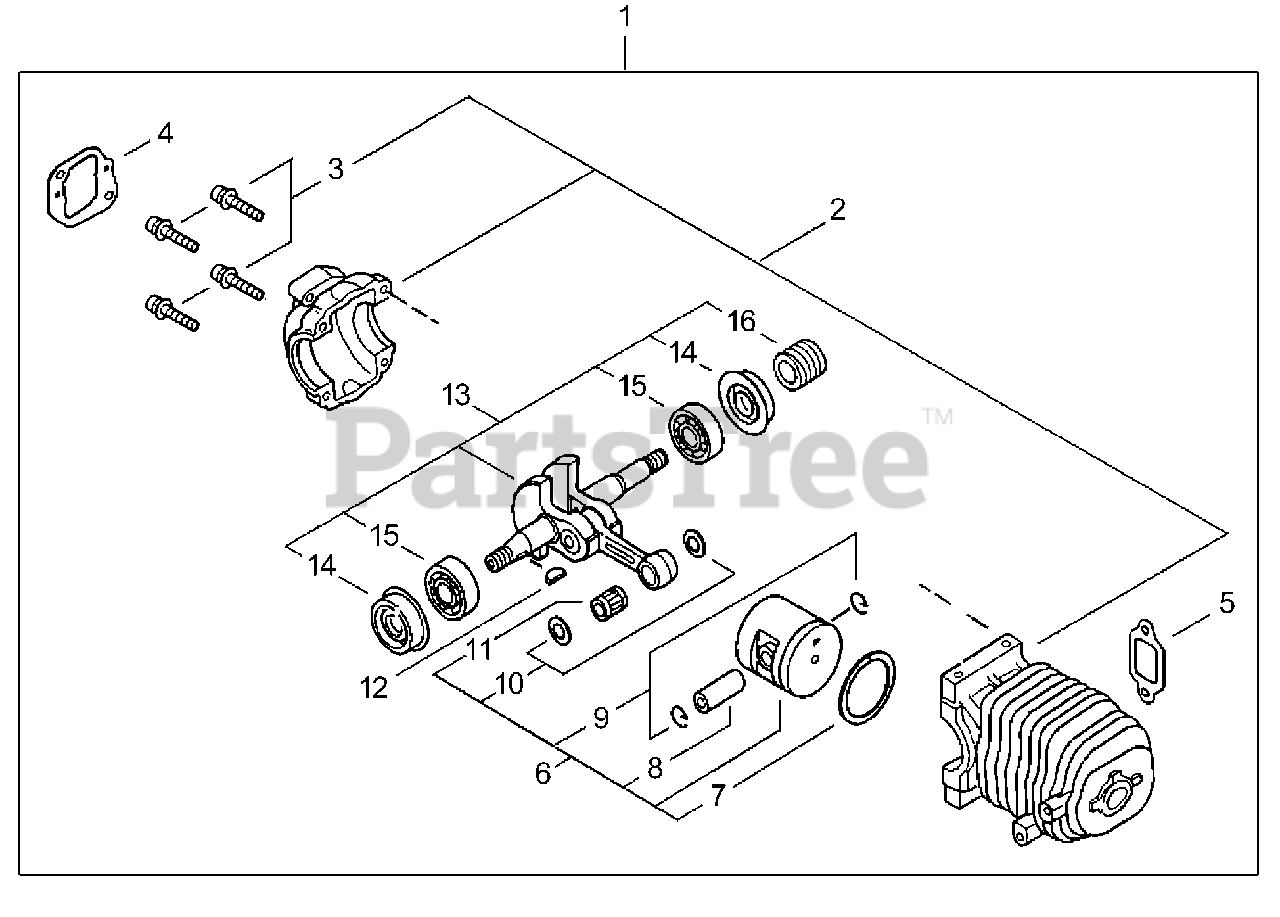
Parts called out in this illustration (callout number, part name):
1	SHORT BLOCK CS-3000
2	CYLINDER & CRANKCASE ASSY
3	SCREW 5×25
4	GASKET, INTAKE
5	GASKET, MUFFLER
6	PISTON KIT
7	RING, PISTON
8	PIN, PISTON
9	RING, SNAP
10	WASHER, THRUST
11	BEARING, NEEDLE 8
12	KEY, WOODRUFF
13	CRANKSHAFT ASSY
14	SEAL, OIL 12
15	BEARING, BALL - 6201 C3
16	GEAR, WORM
